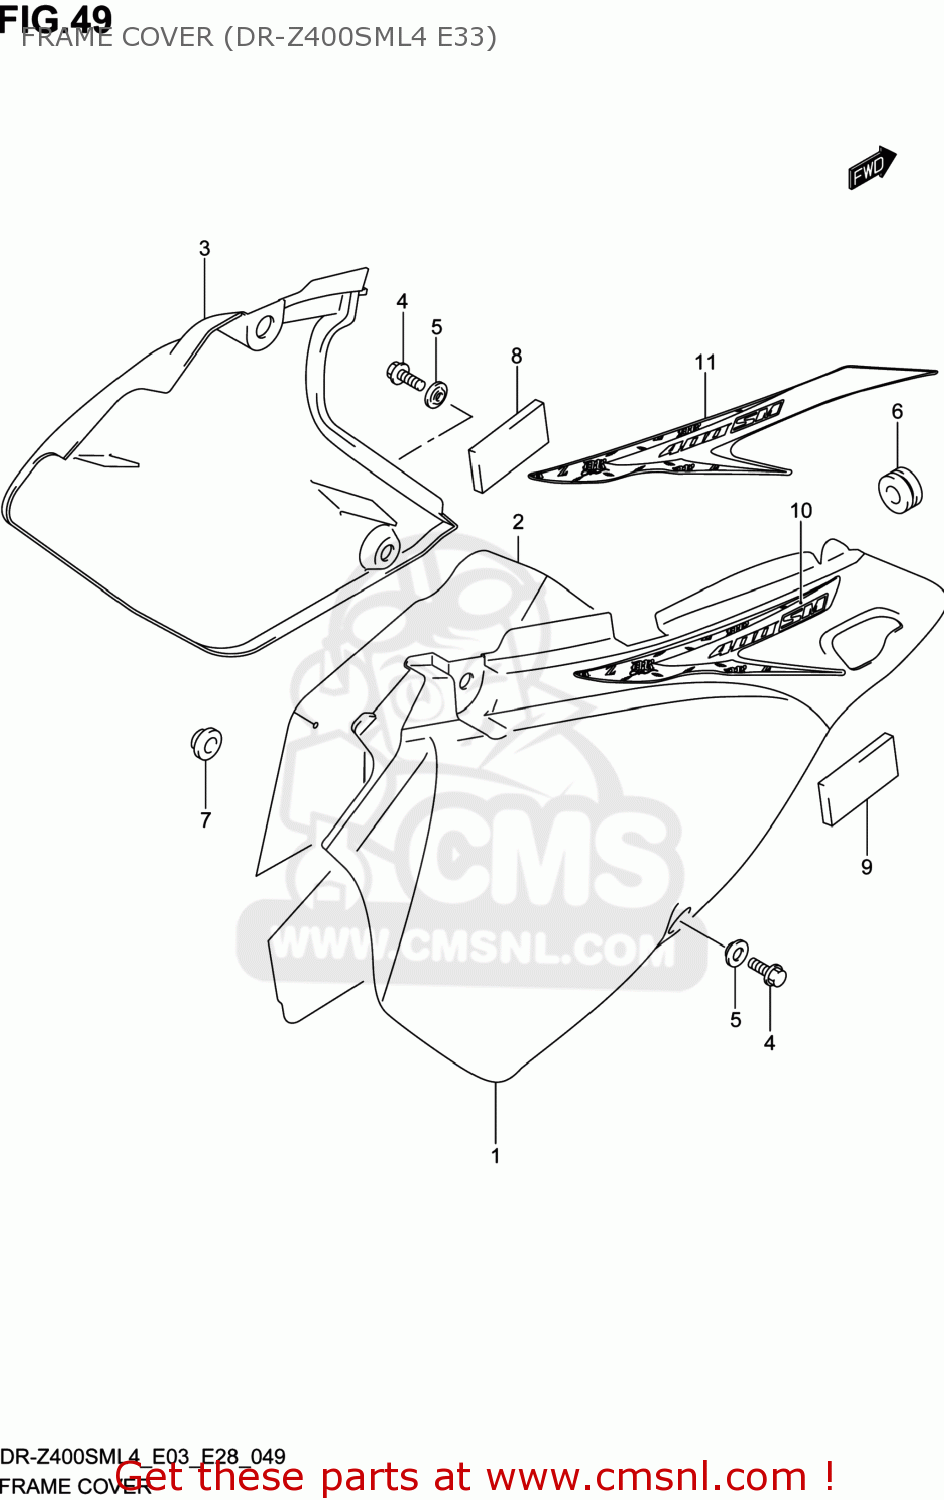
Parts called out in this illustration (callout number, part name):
1	COVER,FRAME,R(BLACK)
2	SHIELD,FRAME COVER,R
3	COVER,FRAME,L(BLACK)
4	BOLT(6X12)
5	WASHER
6	CUSHION
7	CUSHION
8	CUSHION,FRAME COVER,L
9	CUSHION
10	TAPE,FRAME COVER,R
11	TAPE,FRAME COVER,R
